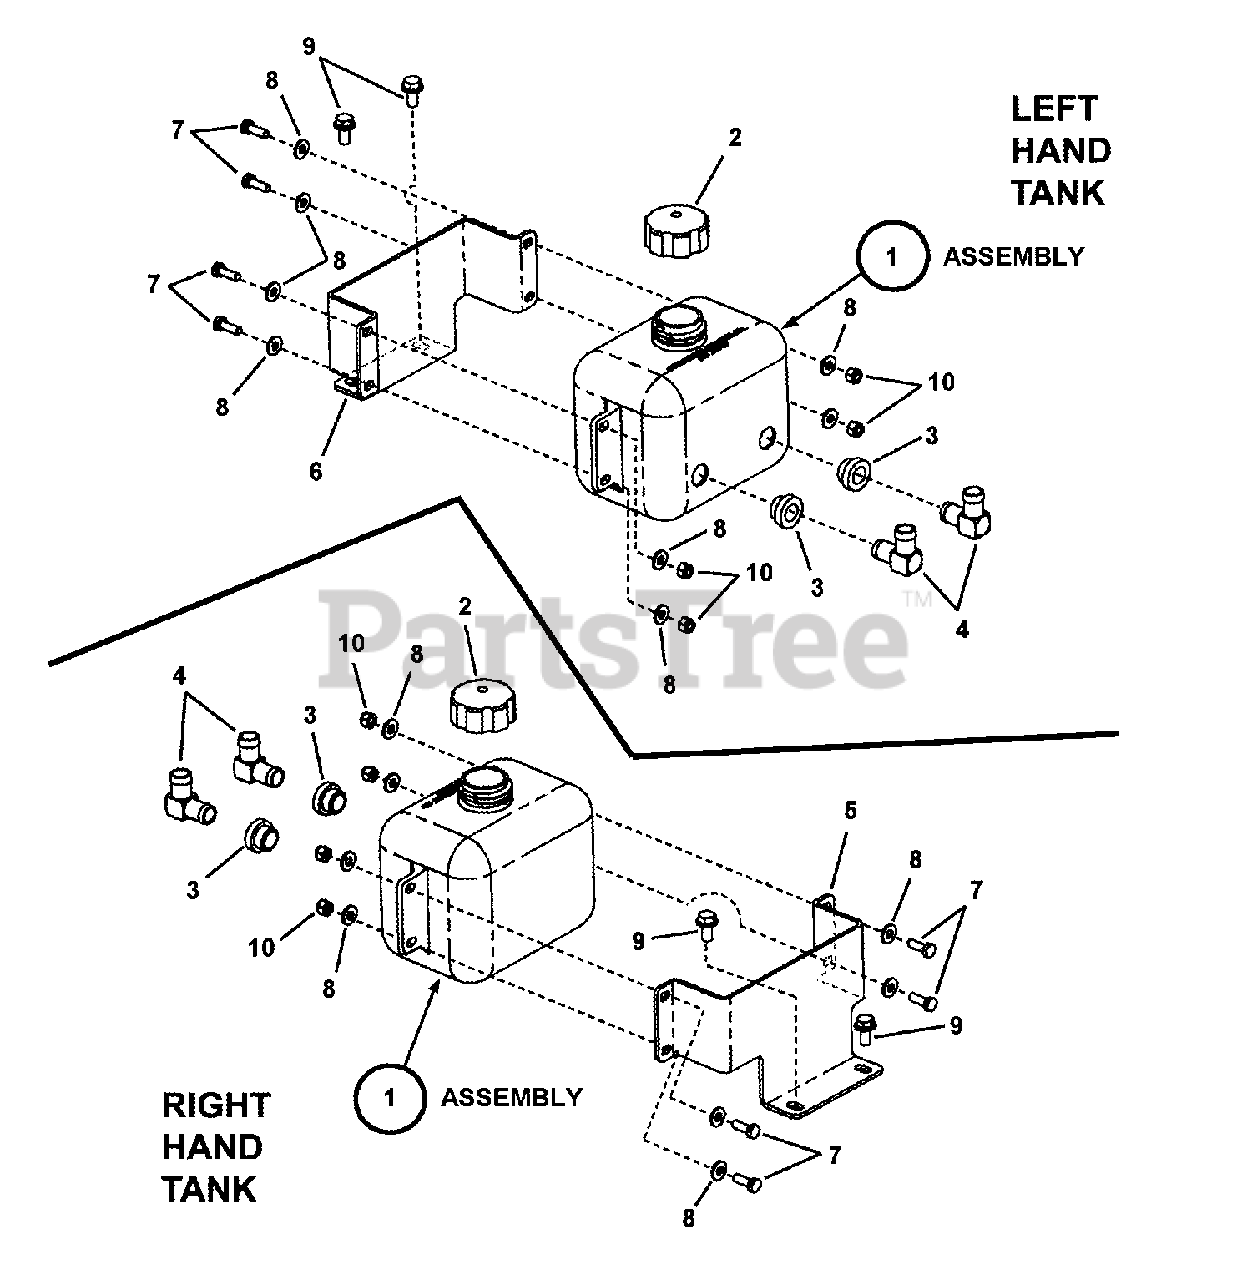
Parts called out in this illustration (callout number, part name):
1	ASSY, Hydraulic Tank (Incl. tank, p/n 7074002 & 3 items shown below)
2	CAP, Vented
3	GROMMET (Dapco #12078)
4	FITTING, #8 Elbox (Dapco #12183)
5	BRACKET, R.H. Hydro Tank Mount
6	BRACKET, L.H. Hydro Tank Mount
7	SCREW, 1/4-20 x 1" Hex Head Cap, GR 5 (or 7027230)
8	WASHER, 1/4" Flat
9	SCREW, 5/16-18 x 5/8" Hex Washer Self-Tap
10	NUT, 1/4-20 HEX NYLON LOCK
